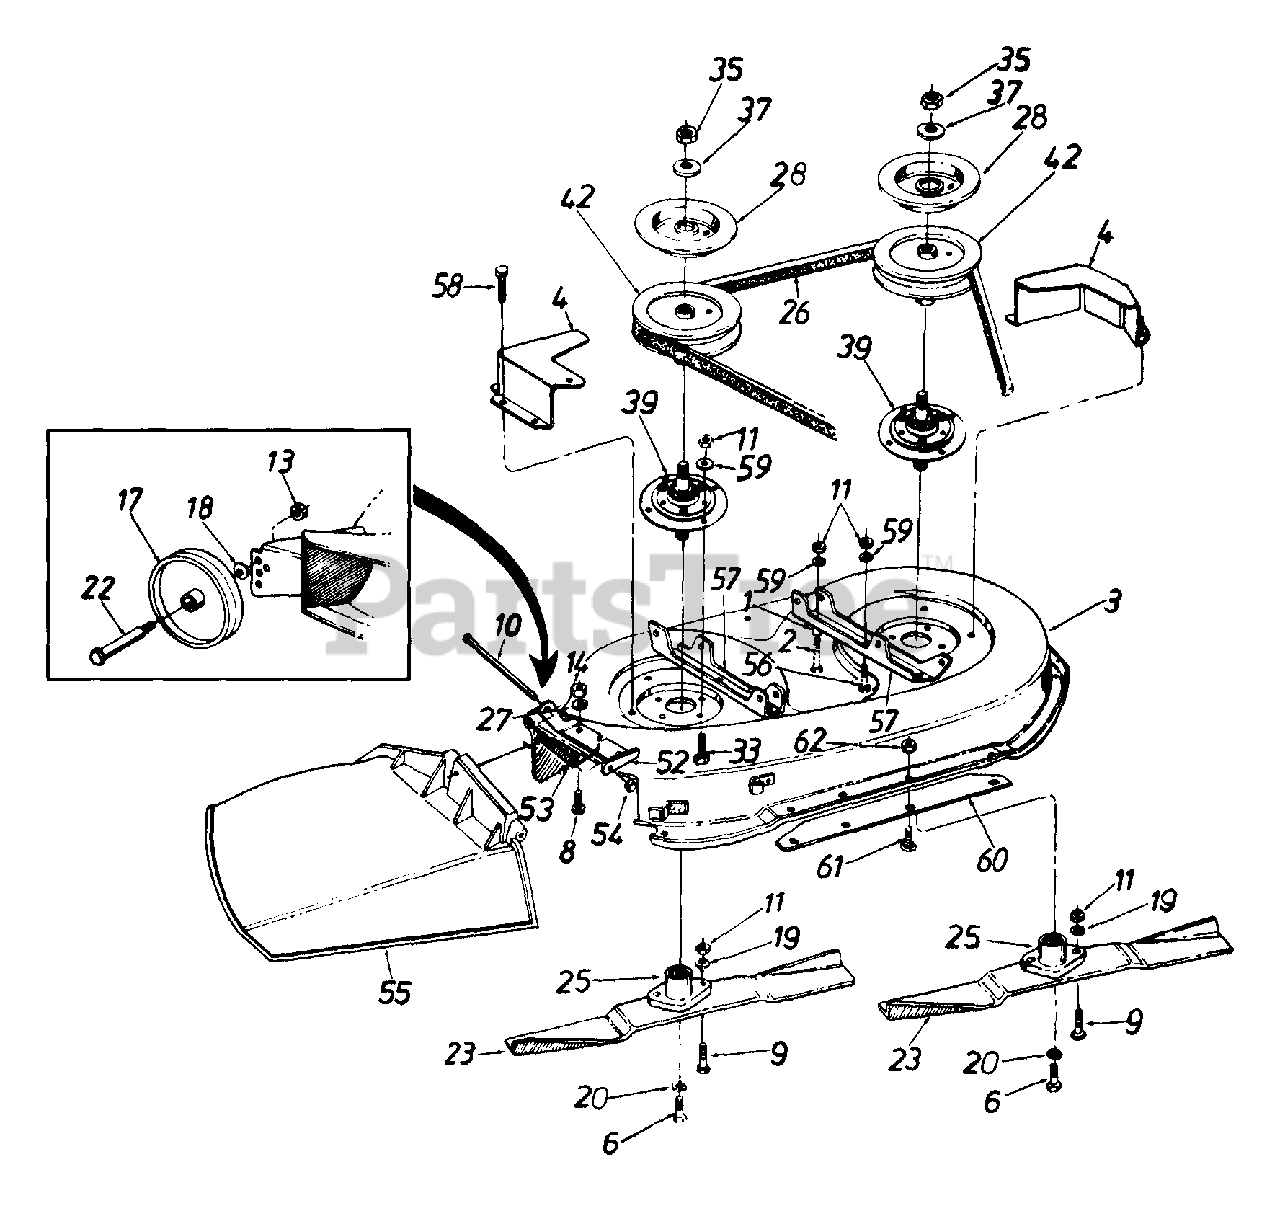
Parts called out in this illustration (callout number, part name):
1	Spacer .33" I D. x .88"
2	Hex Bolt 5/16-24 x 1.25" Lg.
3	38" Deck Ass'y.
6	Hex Bolt 3/8-24 x 1.0" Lg.
8	Hex Bolt 1/4-20 x .62"
9	Hex Bolt Special 5/16-24 x 1.0"
10	Hinge Pin
11	Hex Nut 5/16-24 Thd.
13	Hex Top L-Nut 3/8-16 Thd.t
14	Hex Nut 1/4-20 Thd.
17	Deck Wheel - 5" f
18	Bell - Wash. .40" I.D. x .88" O
19	L-Wash. 5/16" I.D.
20	L-Wash. 3/8" I.D. - H.D.
22	Shld. Bolt .498" Dia. x 1.53"
23	High-Lift Blade
25	Blade Adapter
26	V-Belt
27	Bell-Wash. 1/4" I.D.
28	Brake Disc
33	Hex Bolt 5/16-24 x .75" Lg.
35	Hex Jam Nut 5/8-18 Thd.
37	L-Wash. 5/8" I.D.
39	Blade Spindle Ass'y. Comp.
42	5" Dia. Pulley
52	Hinge Mtg. Brkt.
53	Torsion Spring
54	Push Nut
55	Chute Ass'y. Comp.
56	Hex Bolt 5/16-24 x .75" Lg.
57	Deck Hanger Channel
58	Hex Wash. Hd. TT-Tap Scr. 1/4-20 x .5" Lg.
59	Bell-Wash. .345" I.D. x .88"
60	Skirt Ext.
61	Carr. Bolt 1/4-20 x .5" Lg.
62	Hex Sems Nut 1/4-20 Thd.
